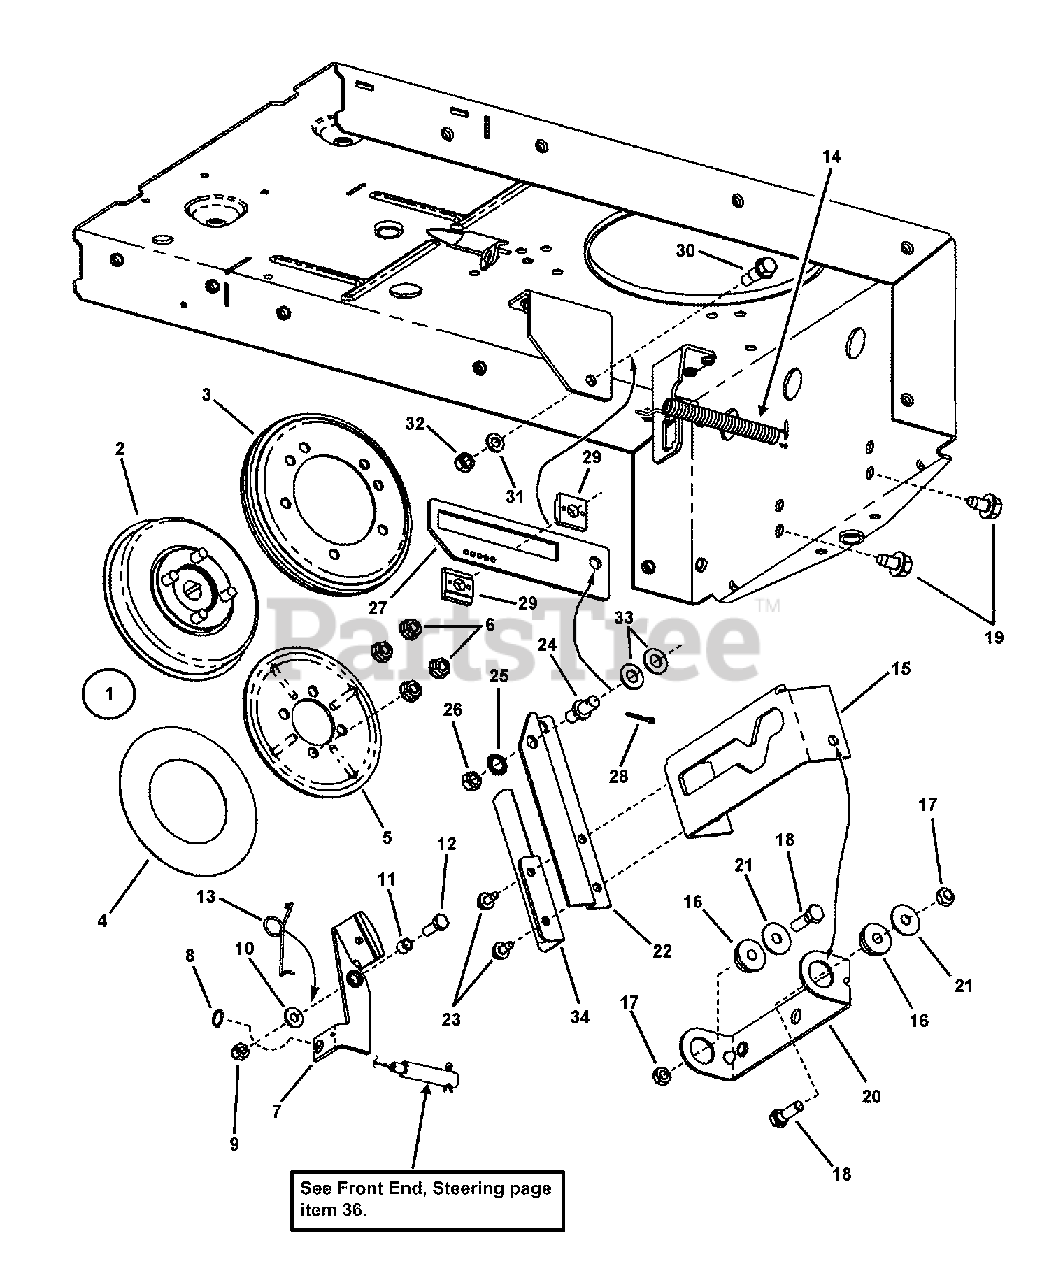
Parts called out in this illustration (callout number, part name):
1	ASSEMBLY, Smooth Clutch (Incl. items 2 thru 6)
2	ASSEMBLY, Driven Disc Hub
3	DISC, Driven (rubber tire bonded to rim)
4	THRUST WASHER
5	PLATE, Drive Disc
6	NUT, 5/16-18 Hex Flange Lock, GR5
7	ASSEMBLY, Brake Lever (Includes brake pad & rivet)
8	RING, 3/8" External Retaining
9	NUT, 1/4-28 Hex Top Lock
10	WASHER, .28 x .63 x .06 Flat, GR5
11	SPACER, Brake Arm Pivot
12	SCREW, 1/4-28 x 1" Hex Head Cap, (Washer Face) GR5
13	SPRING, Torsional Brake Return
14	SPRING, Clutch & Brake
15	LIFT, Yoke
16	BEARING, Yoke
17	NUT, 5/16-24 Hex Center Lock
18	SCREW, 5/16-24 x 1" Hex Head Cap, GR5
19	SCREW, 3/8-16 x 5/8" Hex Washer Self-Tap
20	COLLAR, Yoke
21	FENDER WASHER, 5/16"
22	ARM, Yoke
23	SCREW, 1/4-20 x 1/2" Hex Washer Self-Tap
24	STUD, Clutch Link (3/8-24 thread)
25	WASHER, 3/8" Internal Tooth Lock
26	NUT, 3/8-24 Hex, GR5 or B
27	BRACKET, Slide
28	PIN, 3/32 x 3/4" Cotter
29	SLIDE HALF
30	BOLT, 5/16-18 Shoulder
31	WASHER, 5/16" Split Lock
32	NUT, 5/16-18 Hex, GR 5 or B
33	WASHER, 3/8" Flat SAE
34	ASSEMBLY, Leaf Spring
